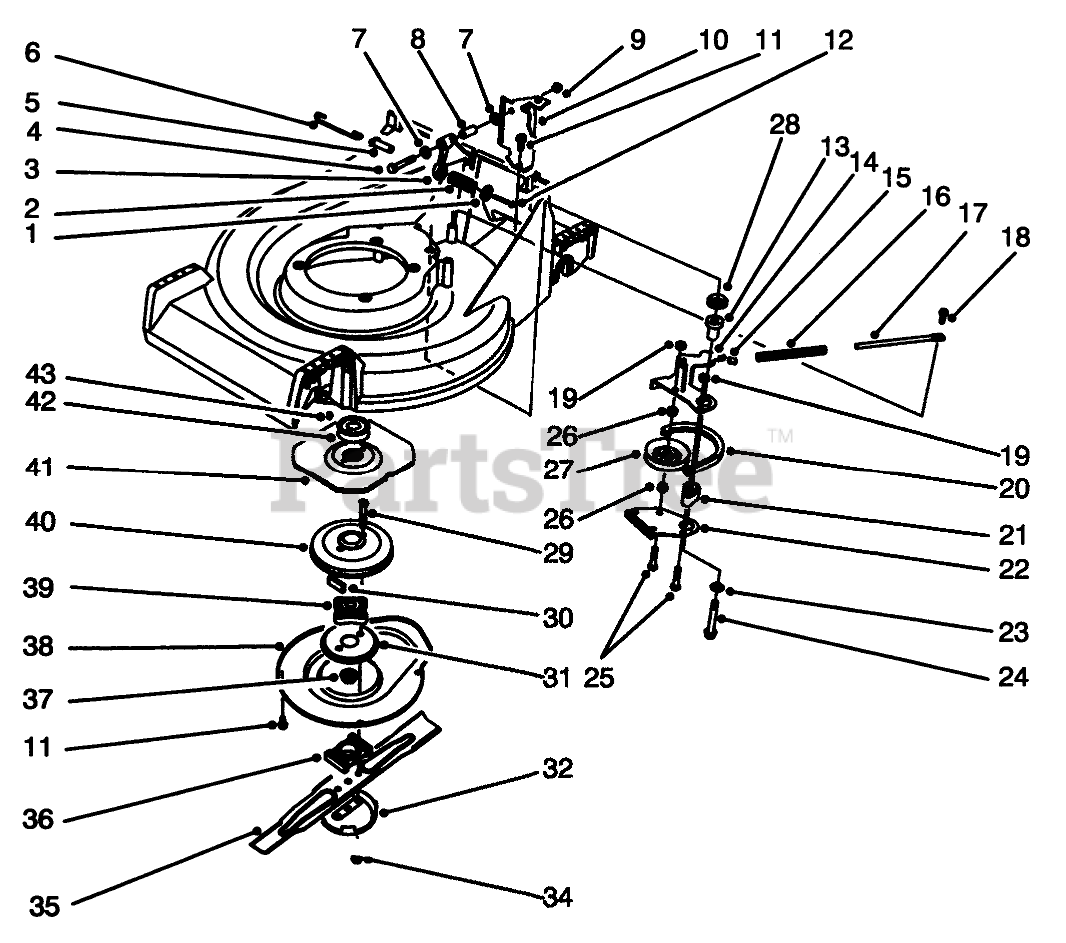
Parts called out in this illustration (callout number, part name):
1	RETAINER-SPRING
2	COMPRESSION SPRING
3	CRANK
4	SCREW-HH
5	SPRING PIN
6	CONTROL LINK
7	WASHER-PLAIN
8	STRAIGHT BUSHING
10	Bracket-Cable Support
11	SCREW-HWHTF
12	SCREW-HWHTF
13	BBC PM BUSHING
14	Lever
15	SPACER
16	COMPRESSION SPRING
17	SPRING ROD
18	SCREW-SHOULDER
19	NUT-LOCK, NI
20	V-BELT
21	BRAKE PLATE HUB
22	BRAKE SHOE
23	WASHER-PLAIN
24	THD FORM SCREW
25	SCREW-HH
26	IDLER PULLEY HUB
27	PULLEY-IDLER
28	V-RING SEAL
29	BOLT-BLADE
30	DAMPENER-VIBRATION
31	Screen-BBC
32	CUP-SCALP, ANTI
34	NUT-LOCK
35	Key
36	SPACER-BLADE
37	NUT-LOCK, NI
38	Cover
39	HUB ASM
40	BRAKE DRUM
41	FLYWHEEL - BBC
42	PULLEY
43	KEY-WOODRUFF
